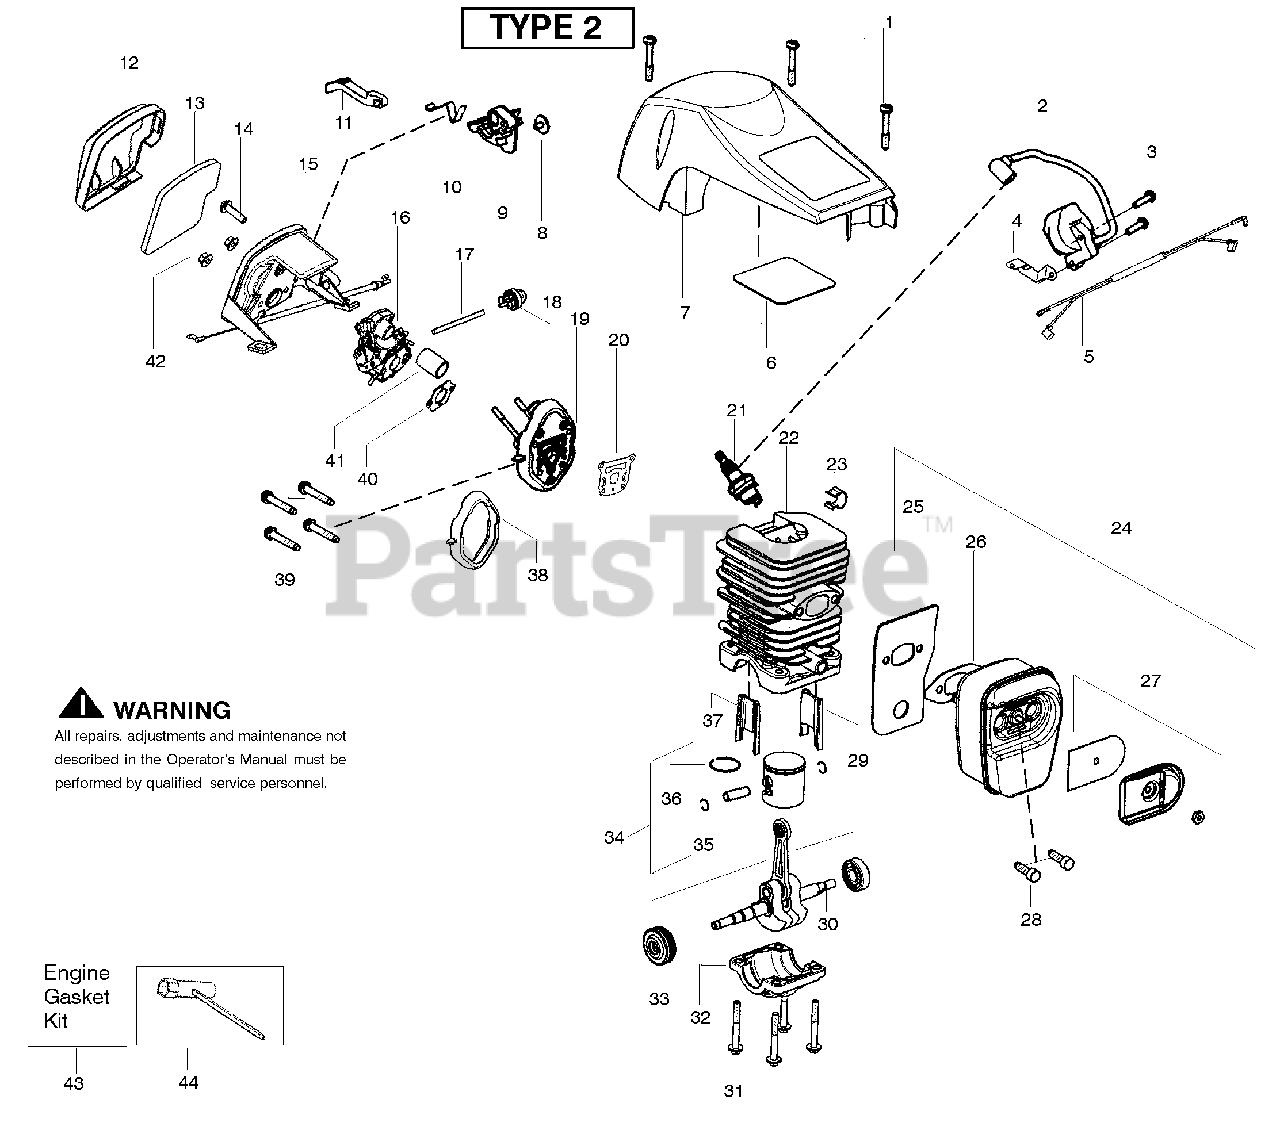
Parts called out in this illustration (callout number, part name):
2	Module-Ignition
4	Strap-Ground
5	Assy-Wire Harness
6	Reflector-Tape
7	Shield-Cylinder
9	Lever-Ignition Switch
10	Spring-Ignition Switch
11	Knob-Choke
12	Cover-Air Filter
13	Filter-Air
15	Housing-Air Filter w/cable
16	Carburetor Zama W26
17	Kit-Fuel Line (Small)
18	Bulb-Purge "snap-in"
19	Kit-Carb. Adaptor
20	Gasket-cyl. o-ring (kit)
21	Accy-Spark Plug (RCJ-7Y)
22	Kit-Cylinder
23	Clip-High Tension Lead
24	Kit-Muffler
25	Ring-Piston
26	Insert-Right (gray)Cyl.
27	Seal-Adaptor (kit)
29	Gasket-Carb. (kit)
30	Tube-Intake
31	Nut-Carb.
32	Kit-Gasket
33	Wrench-Bar
34	Kit-Piston
35	Retainer-Piston Pin
36	Ring-Piston
37	Insert-Right (gray)Cyl.
38	Seal-Adaptor (kit)
40	Gasket-Carb. (kit)
41	Tube-Intake
42	Nut-Carb.
43	Kit-Gasket
44	Wrench-Bar
